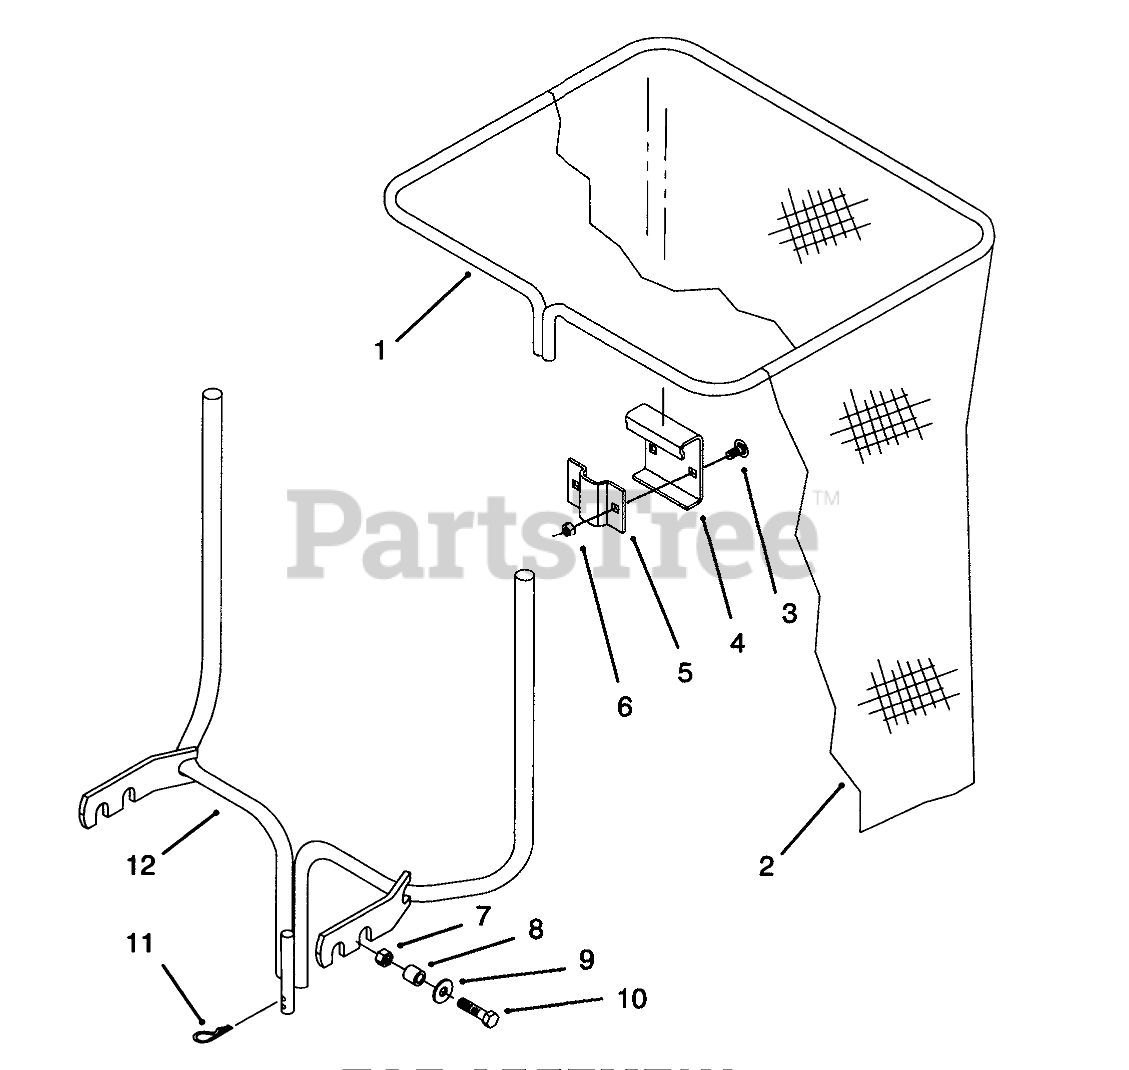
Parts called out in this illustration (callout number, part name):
1	Bag Frame
2	BAG-DEPTH
3	BOLT-CARR
4	Bag Hanger
5	Clamp
6	NUT-LOCK, NI
7	NUT-LOCK, NI
8	SPACER
9	Washer
10	SCREW-HH
11	PIN-COTTER, HAIR
12	WA - BAGGER BRACKET B
